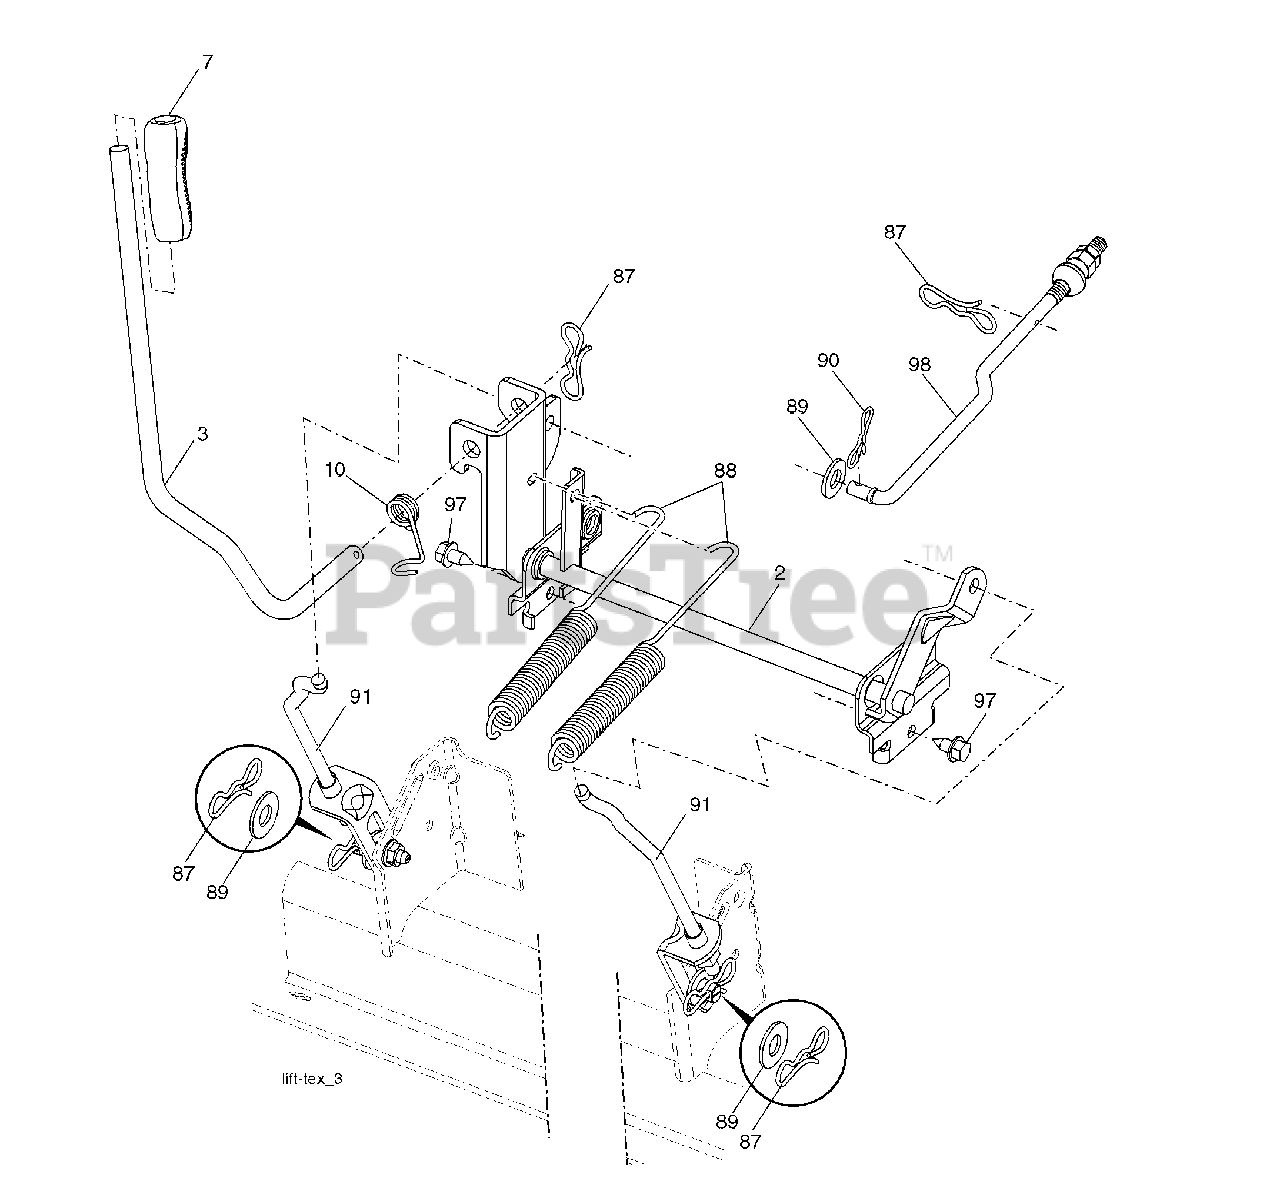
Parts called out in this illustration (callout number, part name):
2	Shaft Asm., Lift
3	Lever Asm., Lift Rh
7	Grip, Lever
10	Spring Torsion
87	Pin Cotter 7/16 Bow Tie Lock
88	Spring Lift Assist
89	Washer Clear Zinc
90	Pin Cotter 5/16 Bow Tie Lock
91	Link Asm Lift LH Rear
97	Screw HEx Wsh. THDR 3/8-16 x 3/4
98	Link Lift Susp. Front Mower
